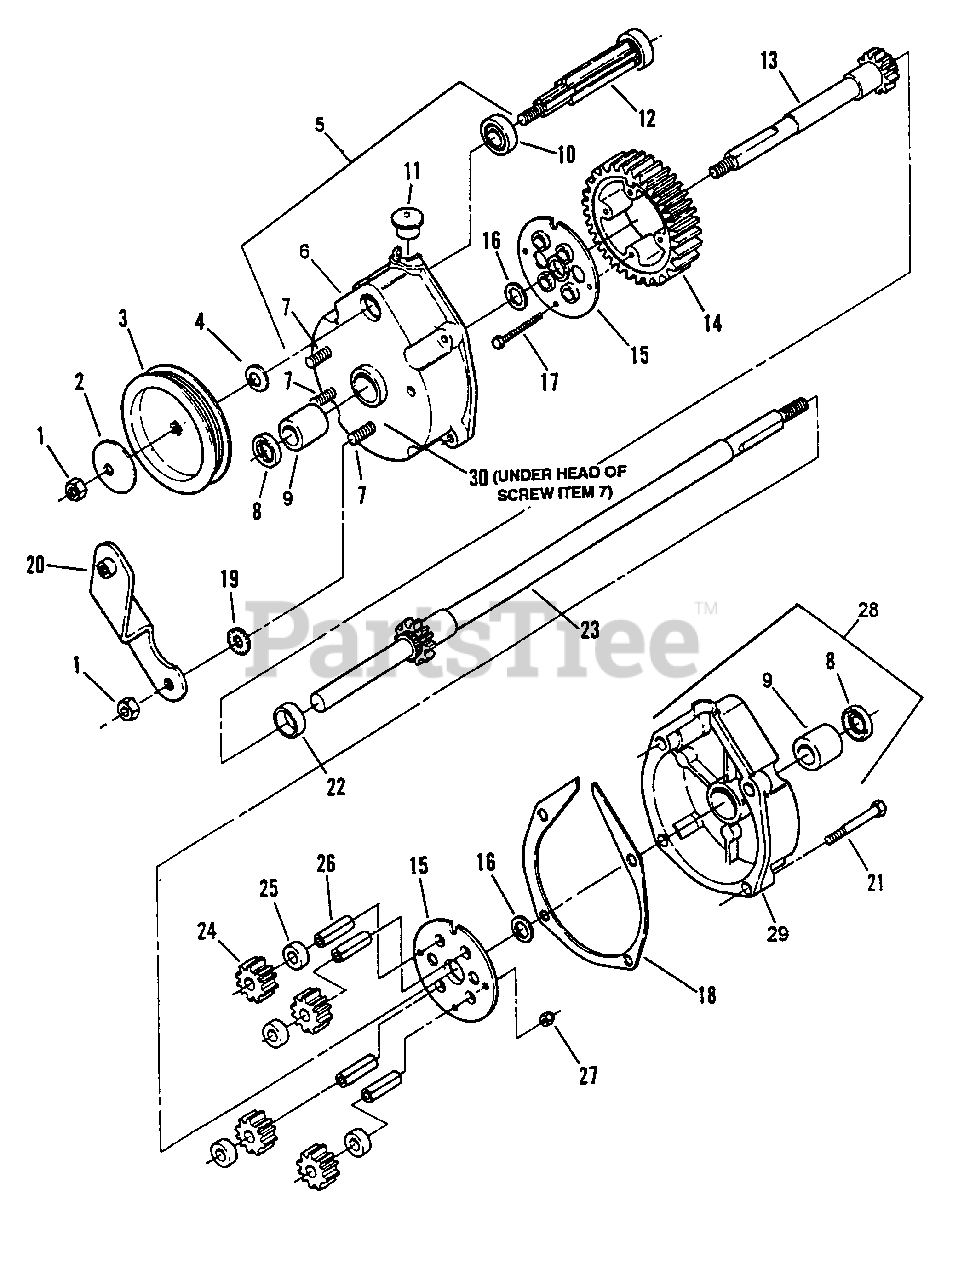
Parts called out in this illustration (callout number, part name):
1	NUT, 5/16-24 Hex Lock, Grade C
2	WASHER, Spring
3	PULLEY, Poly-Vee Belt
4	WASHER, Spring
5	ASSEMBLY, Housing Right
6	HOUSING, Right Side
7	SCREW, 5/16-24 x 1-1/8" Rib Neck, Grade 5
8	SEAL, 5/8 I.D.
9	BEARING, Differential
10	BEARING, Ball
11	PLUG, Housing
12	GEAR, Input (Includes bearing #7073963)
13	AXLE, Short
14	GEAR, Differential (46 Tooth)
15	PLATE
16	WASHER, Thrust
17	SCREW, #10-32 x 1-1/2" Hex Head Cap, Grade 5
18	GASKET, Housing
19	WASHER, 5/16 Internal/External Tooth Lock
20	BRACKET, Differential
21	SCREW, 1/4-20 x 1-1/4" Self-Tapping
22	SPACER, Axle Gear
23	AXLE, Long
24	GEAR, Pinion (12 Tooth)
25	SPACER, Pinion Gear
26	SHAFT, Pinion
27	NUT, #10-32 Hex Nyloc
28	ASSEMBLY, Housing Left
29	HOUSING, Left Side
30	GASKET, 5/8 O.D.
